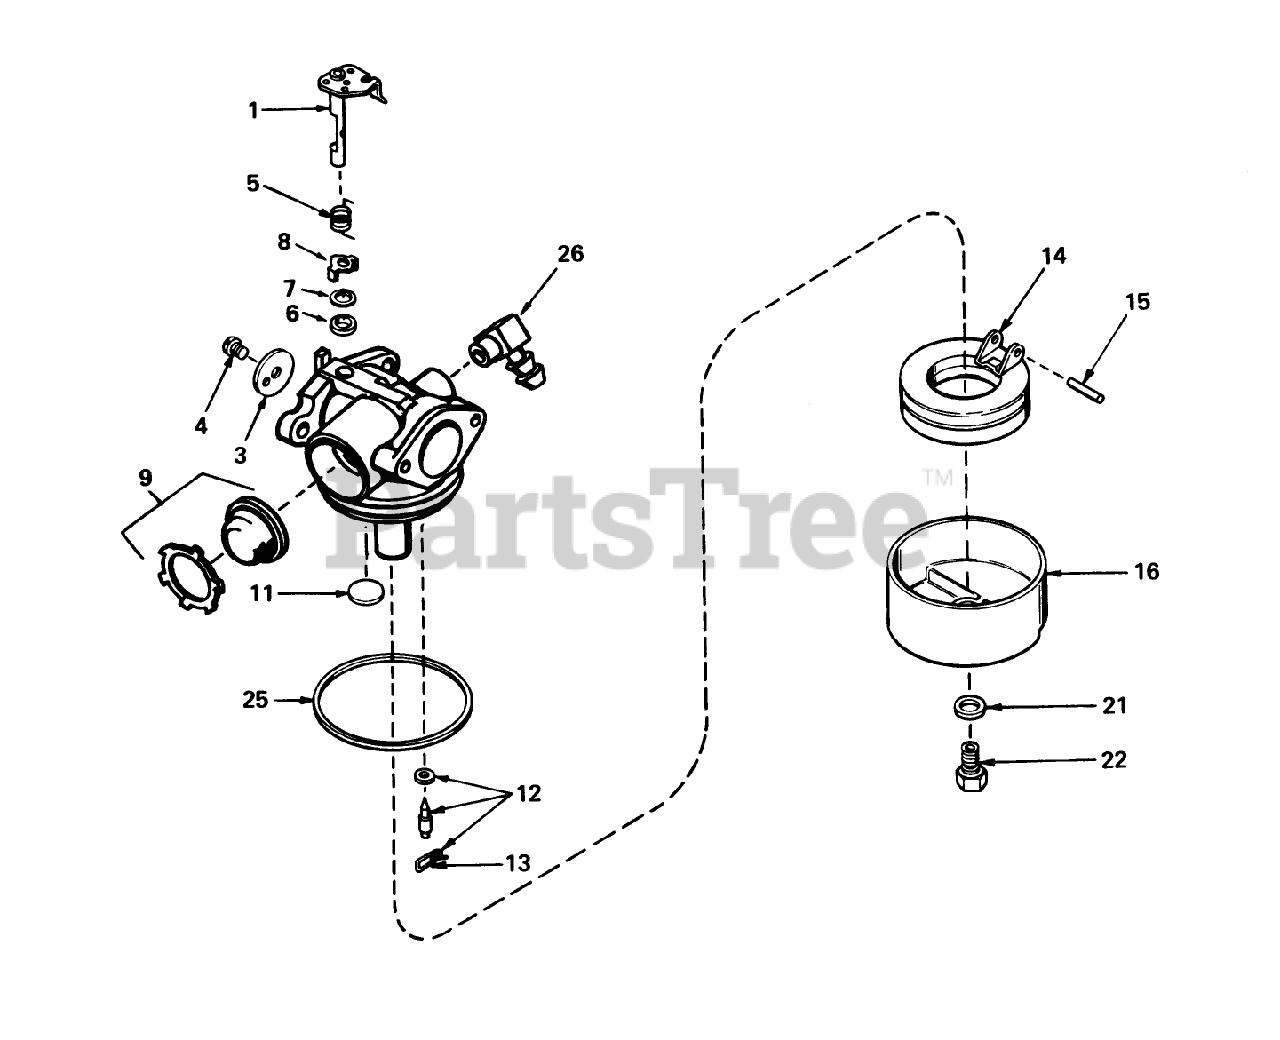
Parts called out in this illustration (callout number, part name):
1	Throttle Shaft and Lever ASM
3	Throttle-Shutter
4	Screw-Shutter
5	Spring, Return
6	Seal-Dust
7	Washer-Seal, Dust
8	Retainer, Seal
9	Primer Assy.
11	Plug-Welch, Atmospheric Vent
12	Inlet Needle, Seat Clip Assy. (Incl. No. 13)
13	Clip-Spring
14	Float
15	Shaft-Float
16	Bowl Float
21	Gasket-Bowl
22	Nut-Float Bowl
25	O Ring-Bowl, Float
26	Fitting-Fuel
